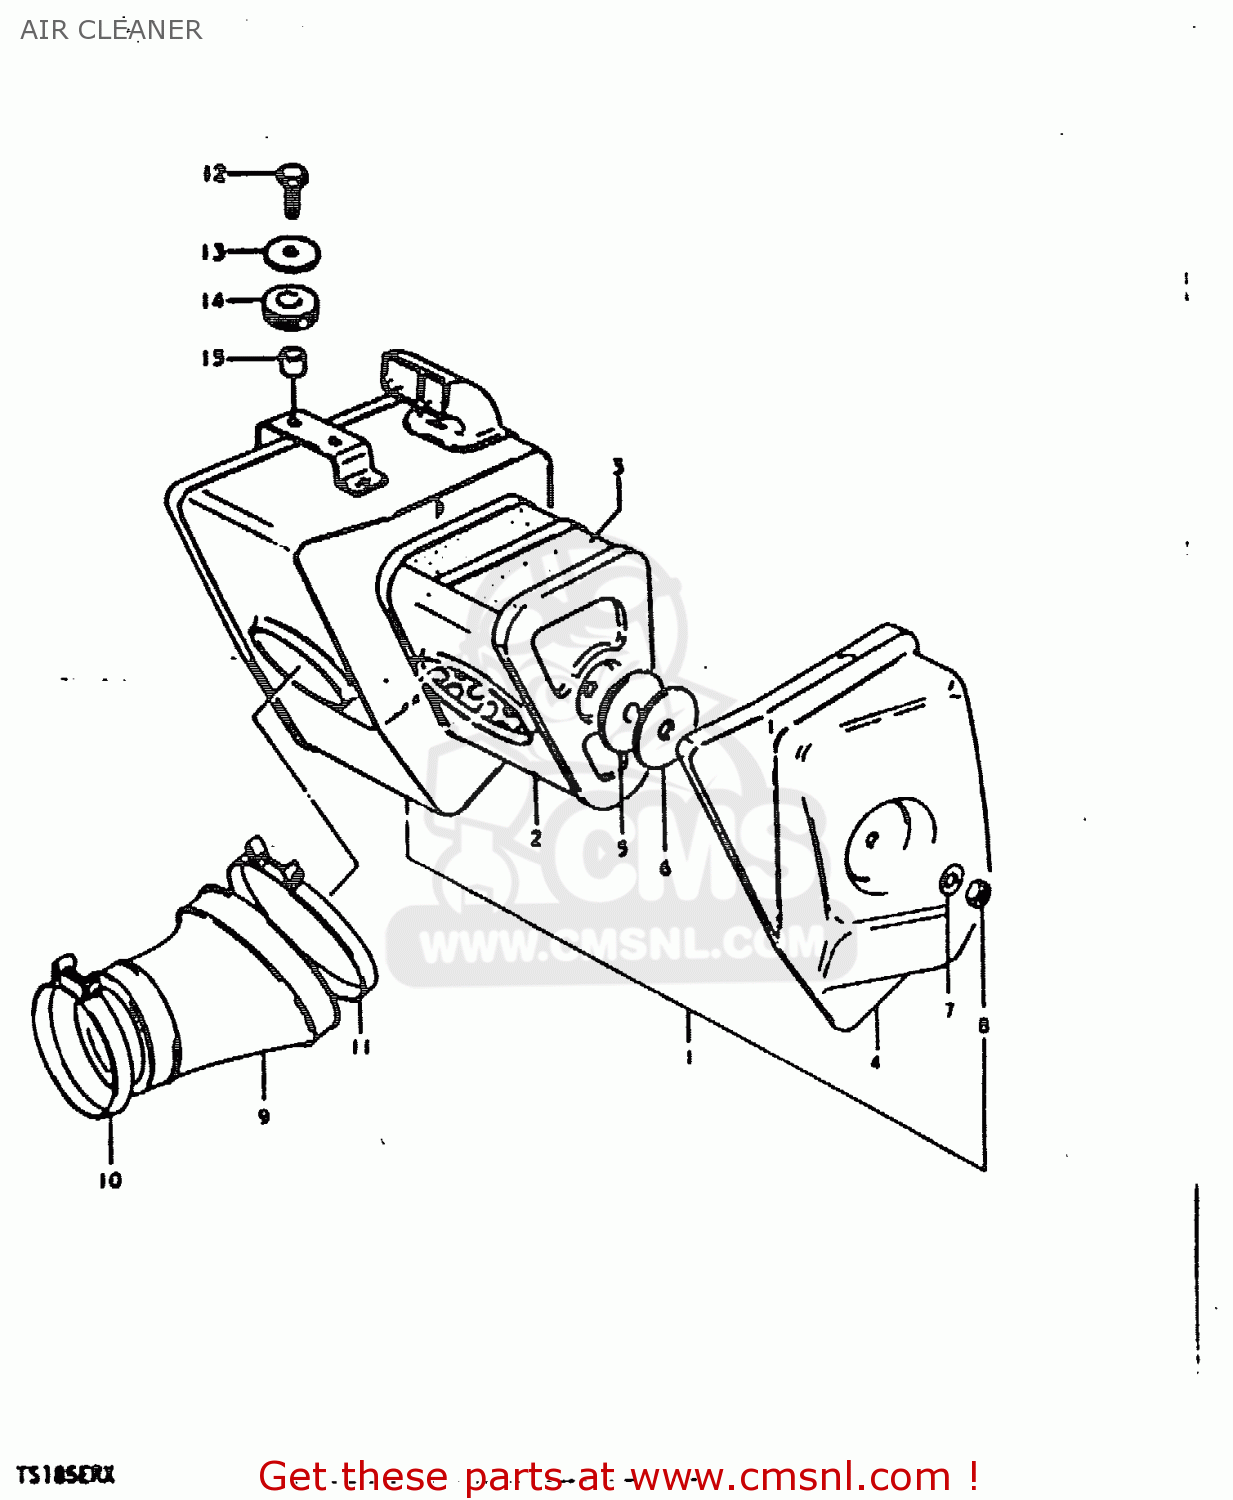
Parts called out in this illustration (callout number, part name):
1	CLEANER ASSEMBLY,AIR
2	FILTER ASSY,AIR CLEANER
3	FILTER
4	CAP
5	SEAL
6	SPACER
7	WASHER
8	NUT
9	TUBE,AIR CLEANER OUTLET
10	CLAMP
11	CLAMP
12	BOLT, UPPER
13	WASHER (6.5X20X1.2)
14	CUSHION
15	SPACER (7X9X7)
